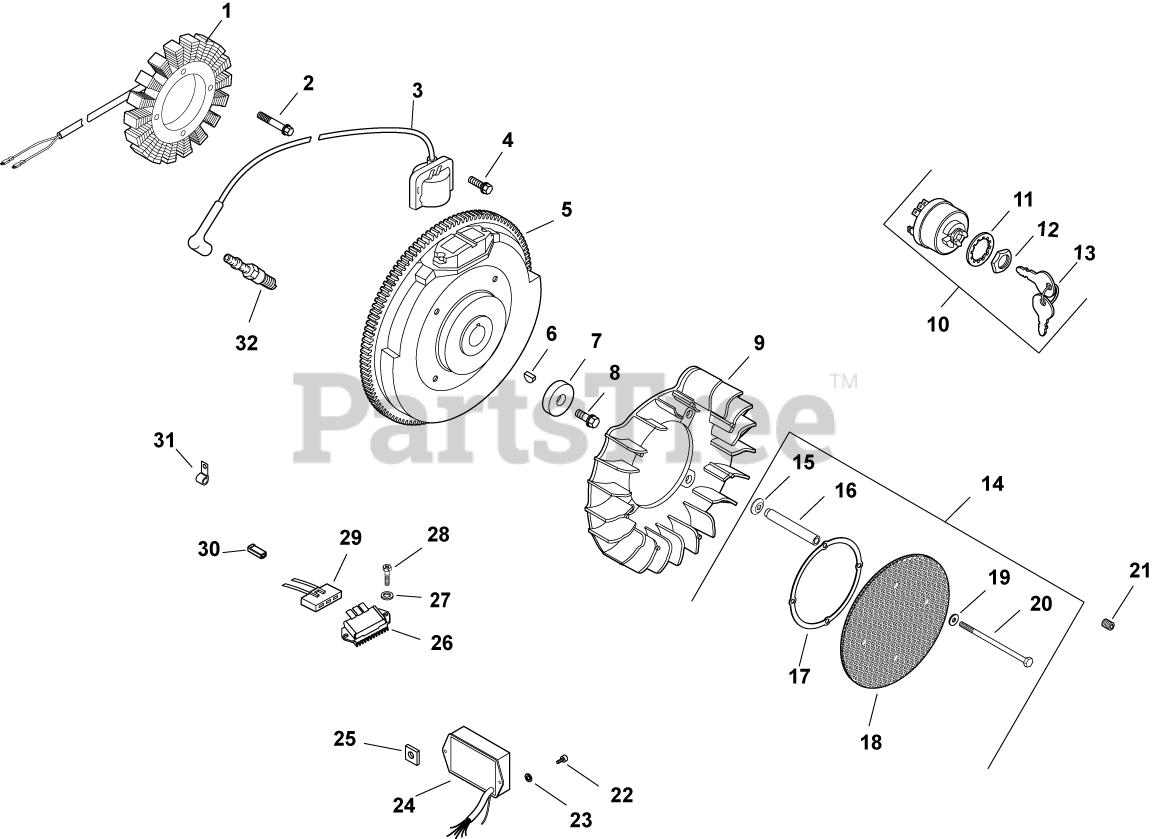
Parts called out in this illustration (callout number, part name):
1	KIT, 15 / 20 AMP STATOR
2	SCREW, M5X0.8X25 - (#25086402S)
3	MODULE, IGNITION
4	SCREW, FLG THD FRM M5X.8X20-(#25086399S)
5	FLYWHEEL ASSEMBLY-USE 24 025 58-S
6	KEY, 3/16" X 5/8"
7	WASHER, FLAT 13/32"
8	SCREW, FLG M10X1.5X45 - (#25086361S)
9	FAN USE 24 755 253-S
10	SWITCH ASSY, KEY (KM)-USE 25 099 32-S
11	WASHER, INTERNAL TOOTH
12	NUT, KEY SWITCH
13	KEY, SET -USE 48 340 01-S
14	KIT, CHOPPER SCREEN
15	WASHER, SPRING 10 MM
17	RING, SUPPORT USE 25 141 08-S
18	SCREEN, GRASS
19	WASHER, FLAT 1/4" (O.D. 5/8")
20	SCREW, CAP M6X1.0X99.5
21	SCREW, SKT SET #10-24X1/4"
22	SCREW, PHL HD #11-16X1/2"
23	WASHER, FLAT 1/4" (O.D. 1/2")
24	MODULE, SPEED ADVANCE -USE 24 755 172-S
25	NUT, PLASTIC
26	REG/RECTIFIER (20/25 AMP)-USE 25 403 20-
27	WASHER, FLAT 3/16"
28	SCREW, PHL HD #11-16X7/8"
29	CONNECTOR, BODY (KM)-USE 25 155 41-S
30	CONNECTOR (1 CONTACT)
31	CLIP, CABLE
32	PLUG, SPARK (PRO SERIES)
2458452-S	MODULE, SPARK ADV -USE 24 584 89-S
